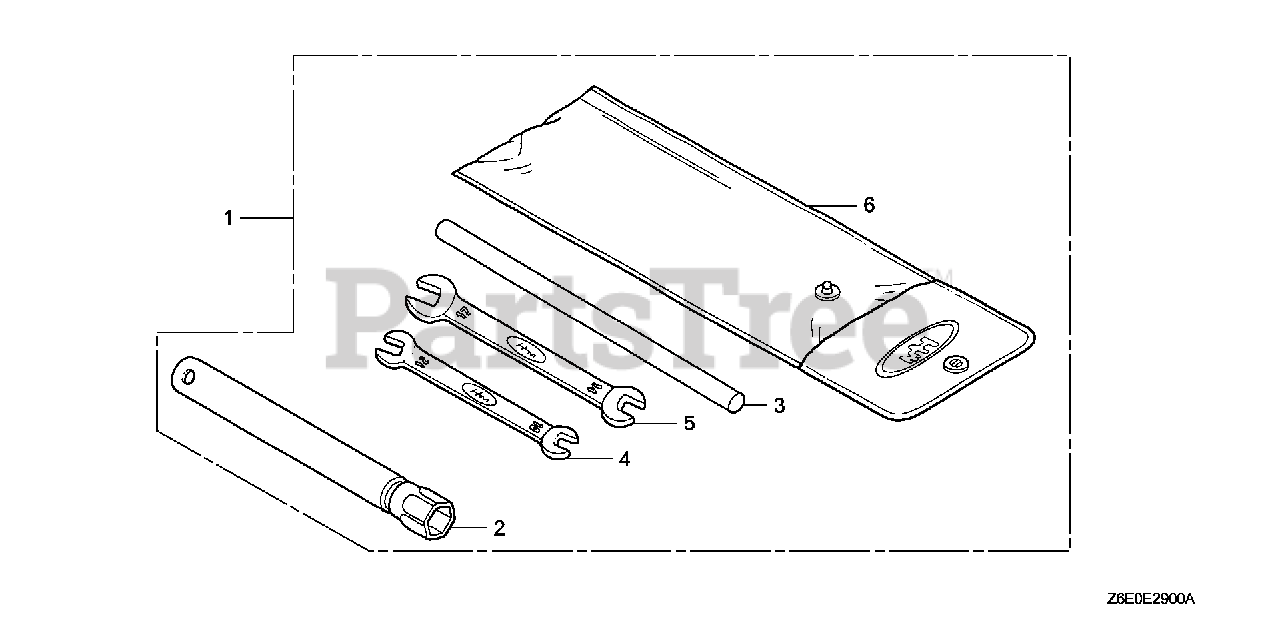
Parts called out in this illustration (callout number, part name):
1	TOOL KIT
2	WRENCH, SPARK PLUG
3	HANDLE, BOX WRENCH
4	SPANNER (10X12)
5	SPANNER (14X17)
6	BAG, TOOL (230MM)
